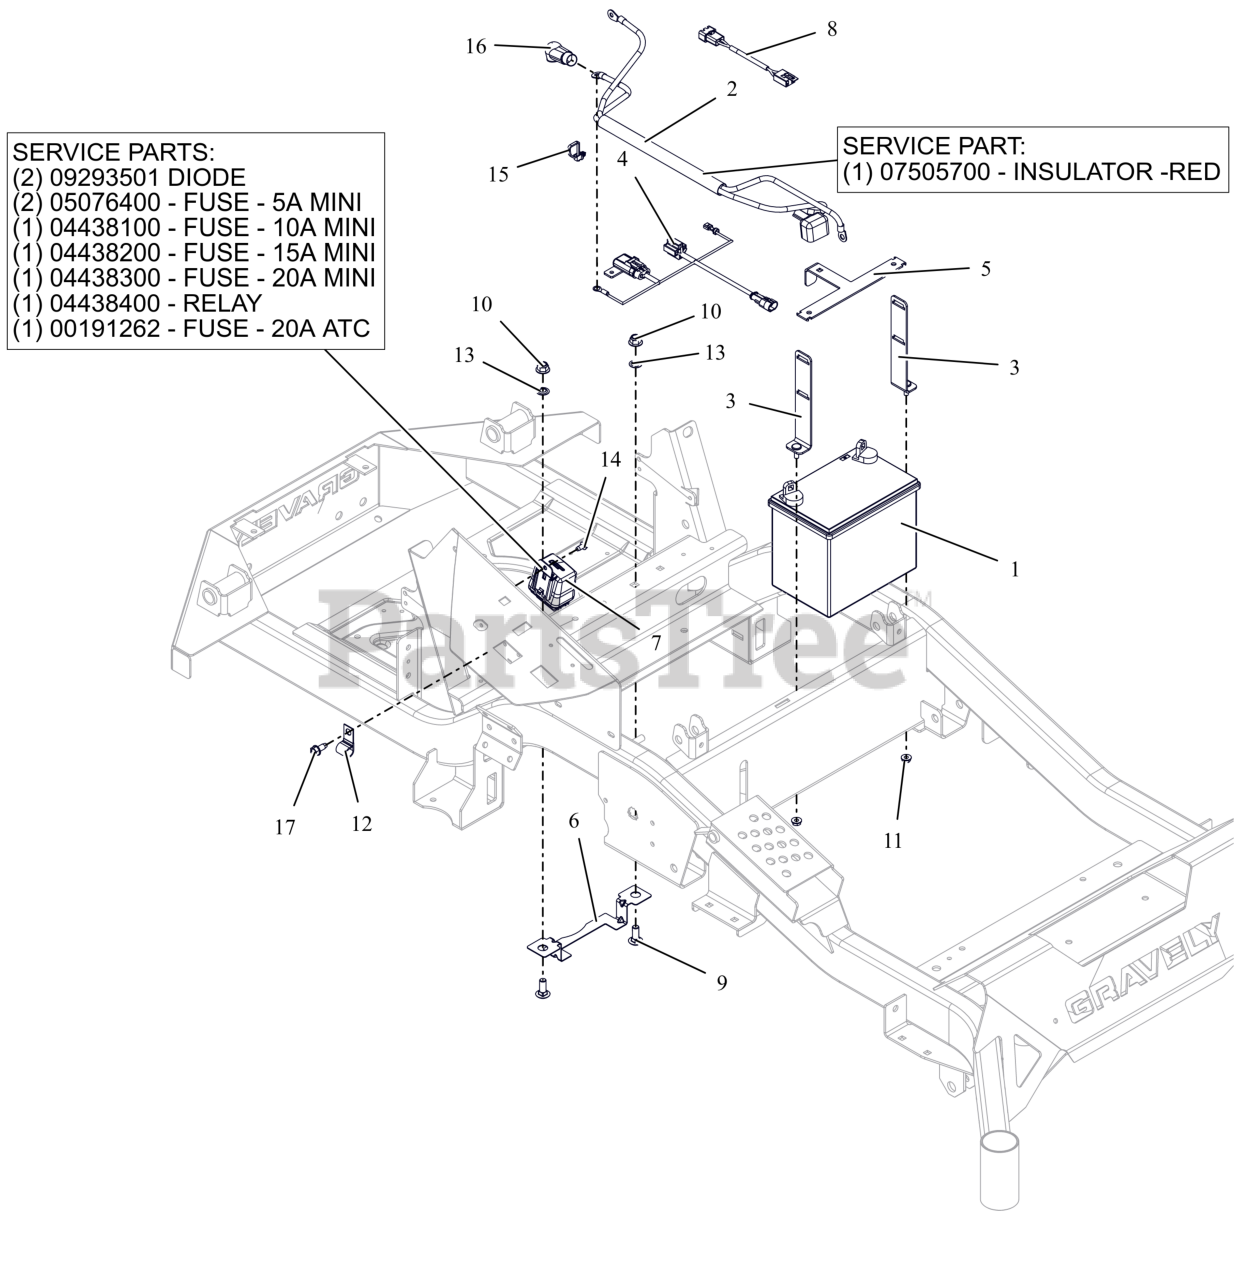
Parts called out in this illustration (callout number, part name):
1	BATTERY, 300 CCA 10U1L
2	HARNESS, BATTERY HD
2	INSULATOR
3	WMT,BATTERY MOUNT HOLD DOWN
4	HARNESS, STARTER ADAPTER
5	BRKT, BATTERY TIE DOWN
6	GUARD, ELECTRICAL HARNESS
7	HARNESS, WIRE
7	DIODE, CONNECTOR SHELL
7	FUSE, 5 AMP MINI-ATC
7	FUSE,10 AMP MINI-ATC
7	FUSE,15 AMP MINI-ATC
7	FUSE,20 AMP MINI ATC
7	RELAY,MICRO5 TERML W/RESISTOR
7	FUSE, 20 AMP BLADE S/O
8	HARNESS- EXTENSION
9	BLT, RHSN .38-16X1.00 G5 ZCC
10	NUT,NYL-FLG .38-16 GF ZCC
11	NUT-LK-TOP-FLG .250-20 GF ZCC
13	NUT-PUSH .38 DIA. PAL ZINC
14	SCR-TAP .25-20X.50 HWH ZCC
15	CABLE TIE W/ TREE (.25 HOLE)
16	BOOT, .65ID POS
17	SCR,TAP .312-18X.75 HWH TR ZCC
